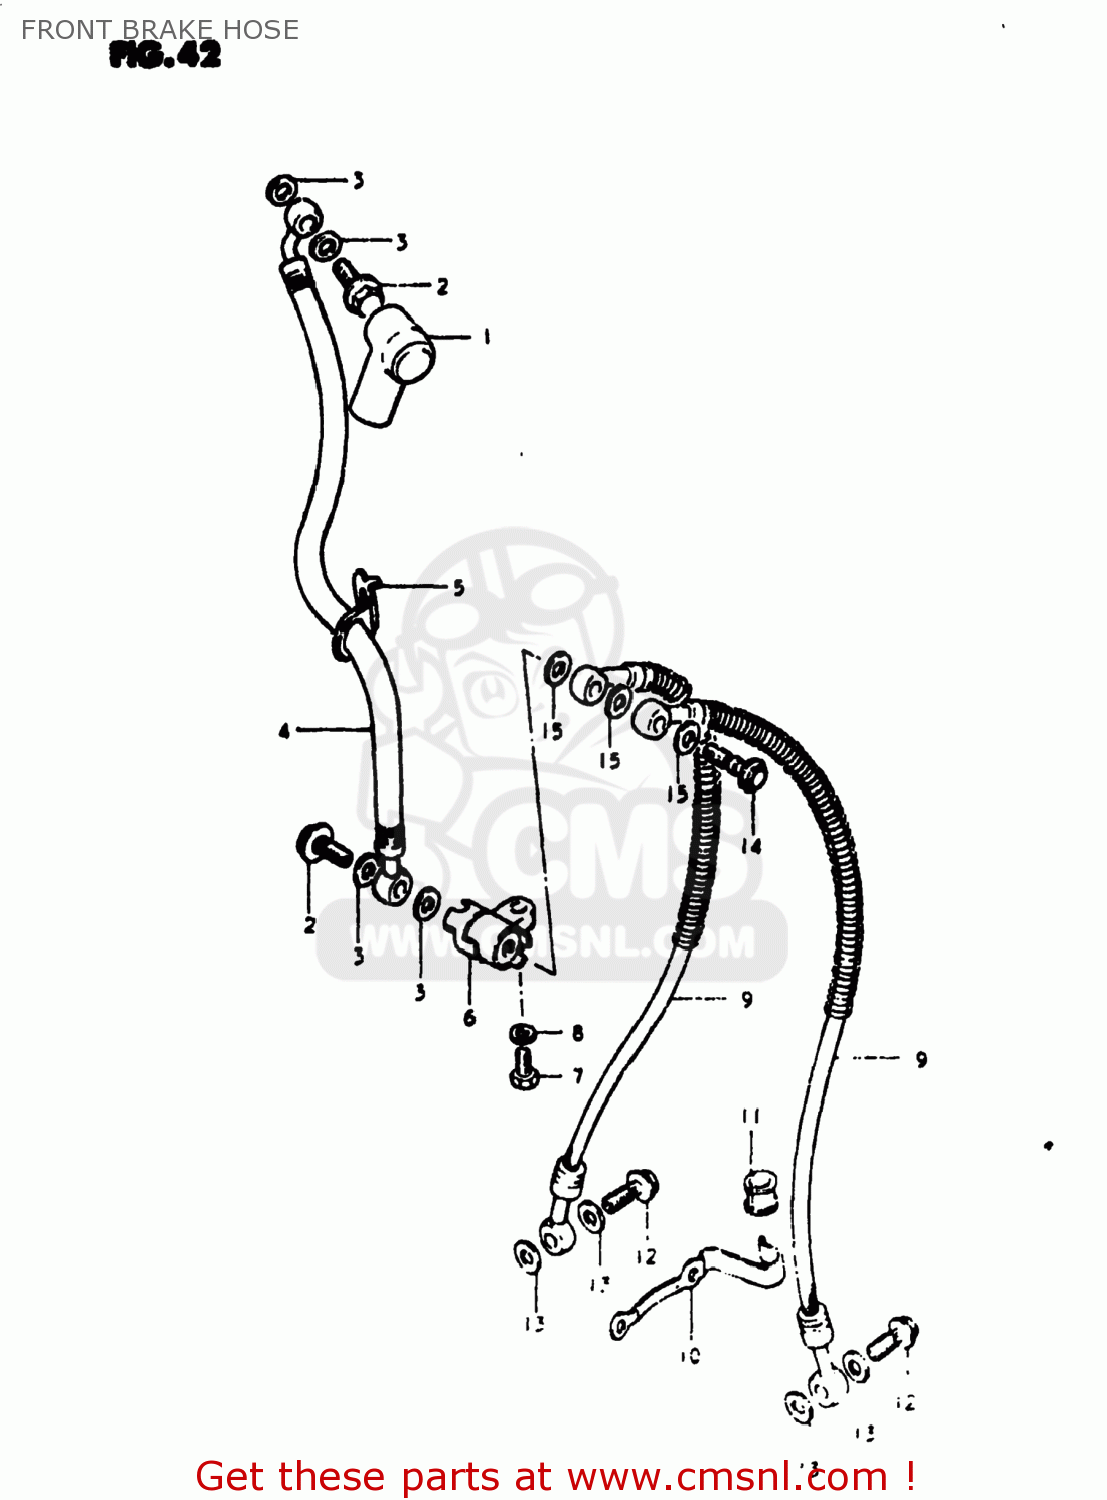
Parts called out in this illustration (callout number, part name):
1	BOOT,MASTER CYLINDER
2	BOLT,UNION
3	WASHER
4	HOSE,FRONT BRAKE
5	GUIDE,BRAKE HOSE
6	JOINT,BRAKE HOSE
7	BOLT
8	LOCK WASHER
9	HOSE,FRONT BRAKE
10	GUIDE,BRAKE HOSE NO.2
11	BUSH,BRAKE HOSE GUIDE,NO.2
12	BOLT,UNION
13	WASHER
14	BOLT,UNION
15	WASHER
